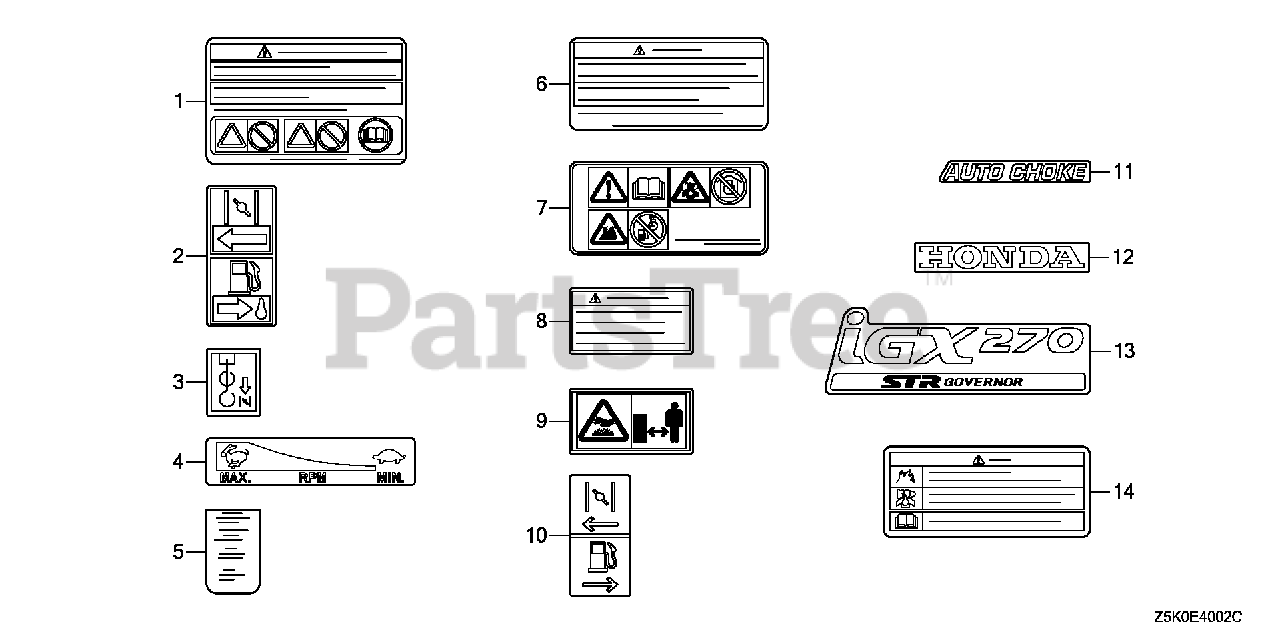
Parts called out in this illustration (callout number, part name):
1	MARK, OPERATOR CAUTION (FRENCH)(MADE IN THAI)
6	MARK, OPERATOR CAUTION (FRENCH)(MADE IN THAI)
7	MARK, OPERATOR CAUTION (PICTOGRAPH)
8	MARK, EX. CAUTION (FRENCH)
